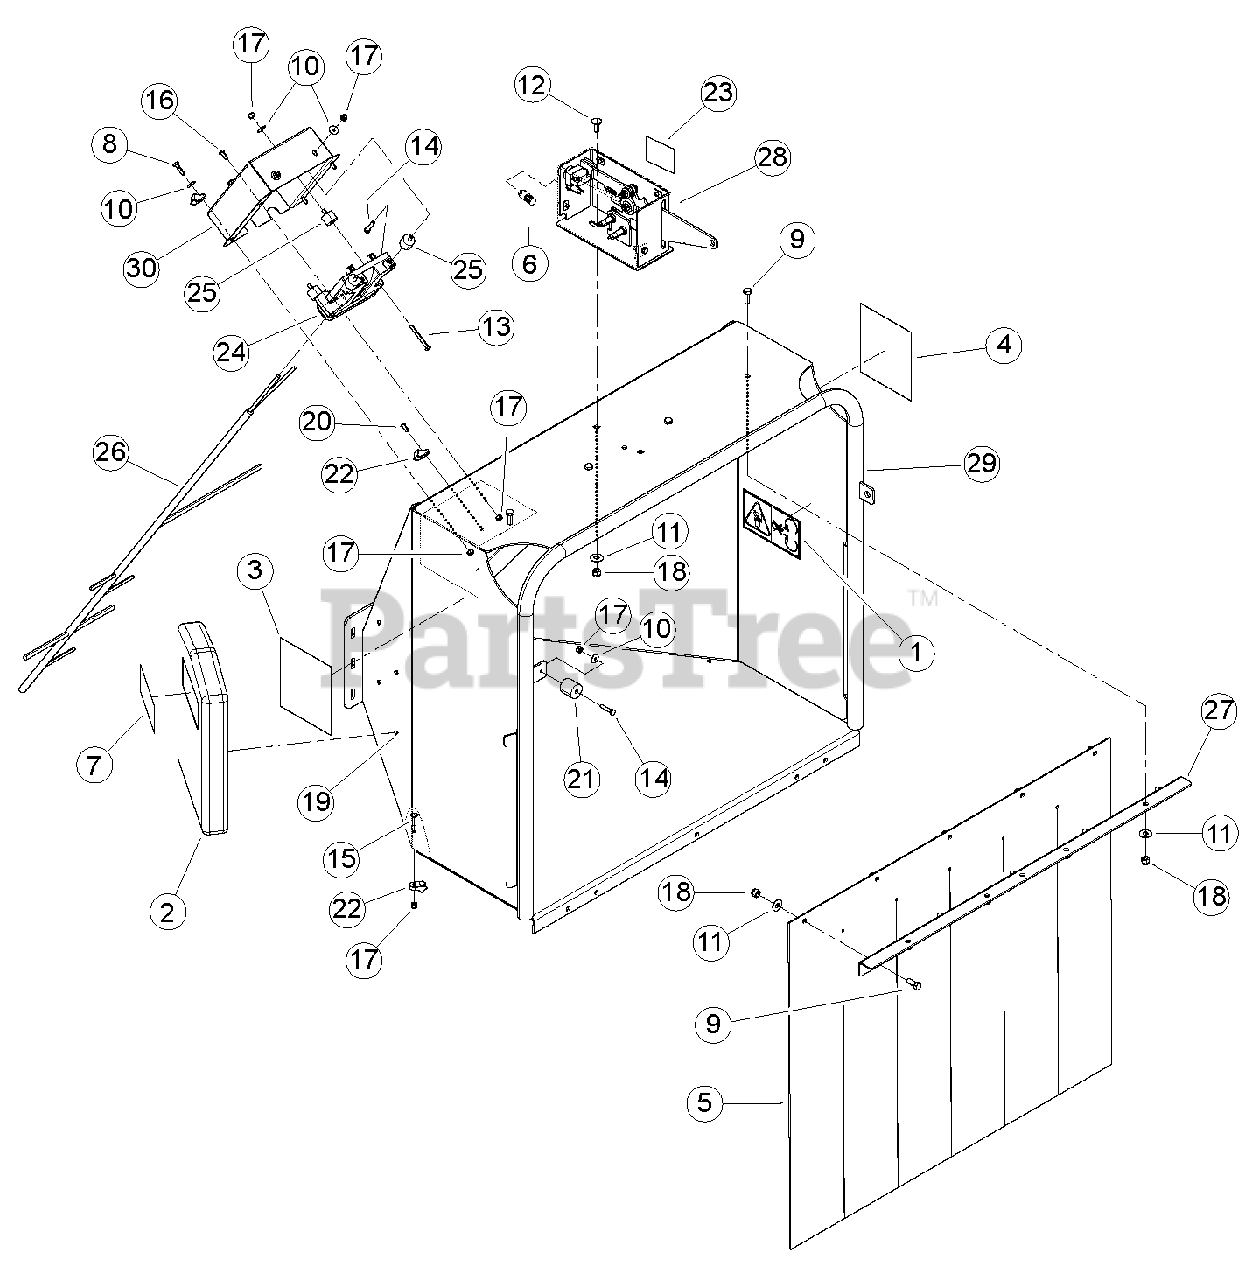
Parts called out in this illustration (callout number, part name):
1	DECAL, BLADE DANGER ISO
2	CONTAINER, INSTR. MANUAL
3	DECAL, FEED POSITION
4	DECAL, FEED POSITION
5	FLAP, CHUTE
7	DECAL, MUTILINGUAL MANUAL
8	BOLT, 1/4 X 1 HEX HD GR5 ZP
9	BOLT, 3/8 X 1 HEX HD GR5 ZP
10	WASHER, 1/4 FLAT ZP
11	WASHER, 3/8 FLAT ZP
12	BOLT, 3/8 X 1 CRG GR5 NC ZP
13	BOLT, 1/4 X 2-1/4 HEX HD GR5 ZP
14	BOLT, 1/4 X 1-1/4 HEX HD GR5 ZP
15	BOLT, 1/4 X 1 CRG GR5 NC ZP
16	BOLT, 1/4 X 5/8 HEX HD GR5 ZP
17	NUT, 1/4 NE NYLOCK ZP
18	NUT, 3/8 NE NYLOCK ZP
19	RIVET, AL BLIND 1/4 X 1/2 DOME HEAD
20	RIVET, AL BLIND 1/4 X 3/4 DOME HEAD
21	BUMPER, RECESSED RUBBER
22	CLAMP, CABLE MOUNT
23	DECAL, RESET/OVERRIDE
24	CONTROLLER, PLUS 1 CHIPPER
25	BUMPER, 1" OD W/1/4" STUD
26	HARNESS, 6IN DIESEL-PLUS 1
27	SUPPORT, CHIPPER FLAP
28	ASSEMBLY, SWITCH BOX
29	WELDMENT, CHIPPER CHUTE
30	ENCLOSURE, PLUS 1 MOUNT
